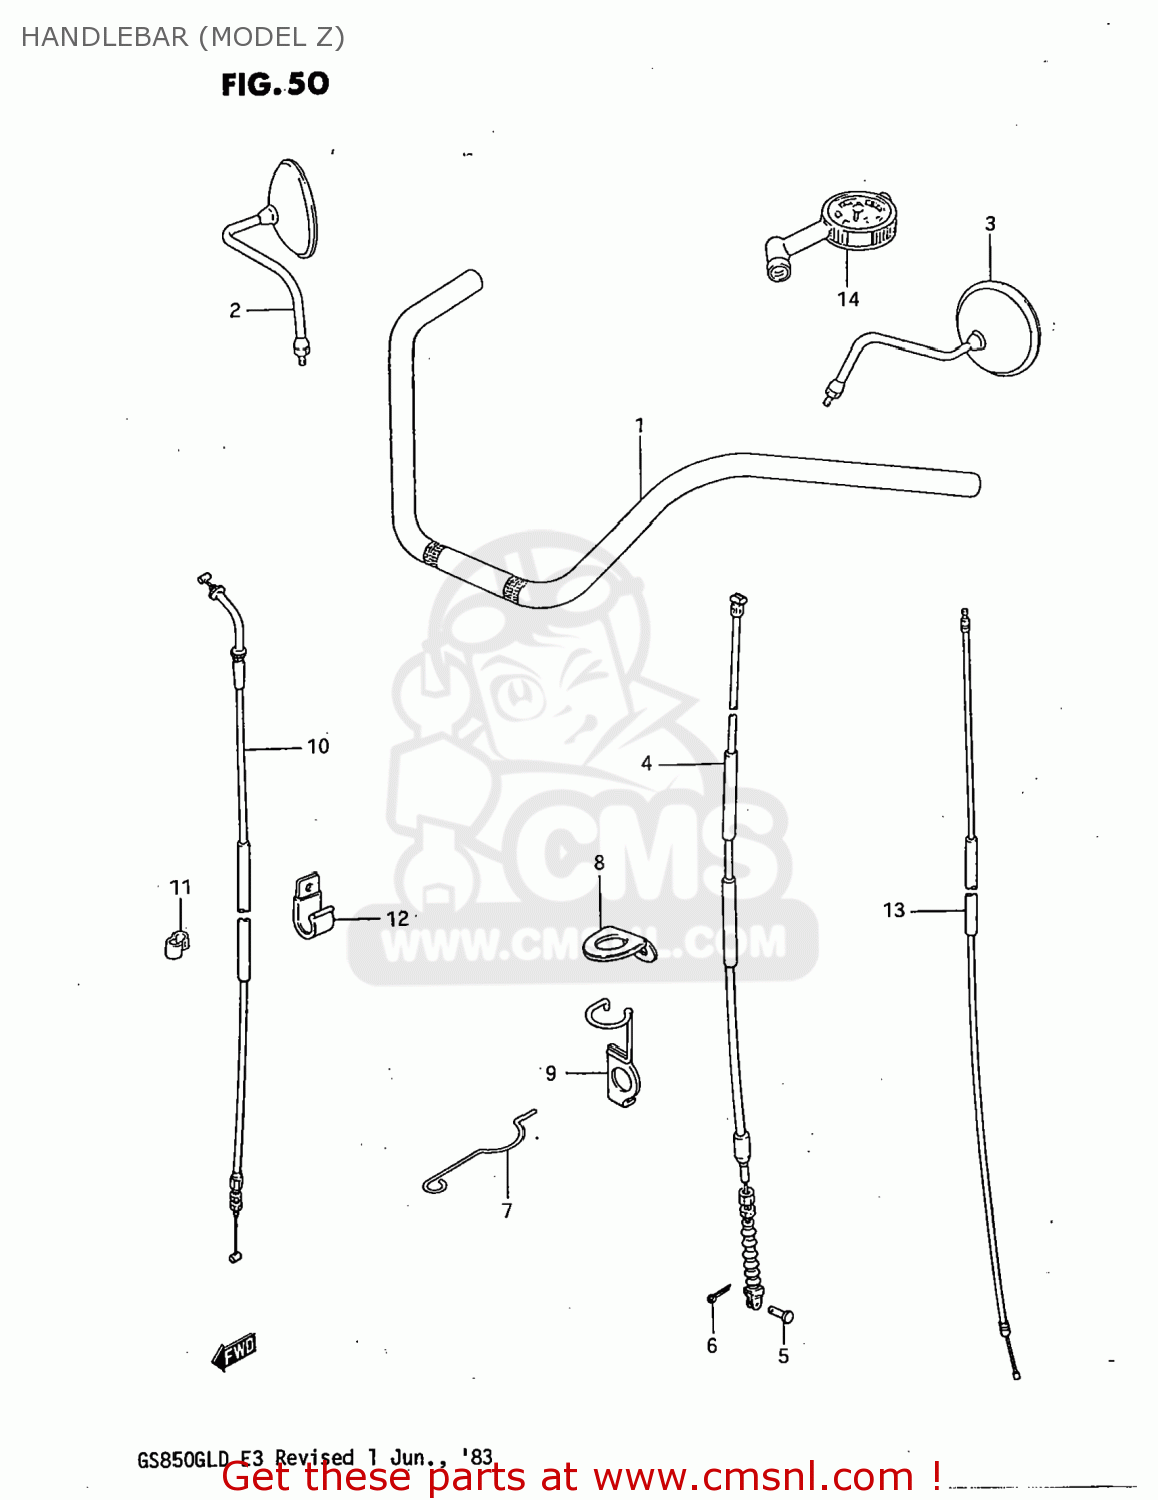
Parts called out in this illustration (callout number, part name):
1	HANDLEBAR
2	MIRROR ASSEMBLY,RIGHT
3	MIRROR ASSEMBLY,LEFT
4	CABLE ASSY,CLUTCH
5	PIN(L:15)
6	PIN
7	GUIDE,CABLE
8	GUIDE,BRAKE HOSE
9	GUIDE,CLUTCH CABLE
10	CABLE ASSEMBLY,THROTTLE
11	CLIP
12	CLAMP
13	CABLE,STARTER
14	GAUGE ASSY,AIR PRESSURE
